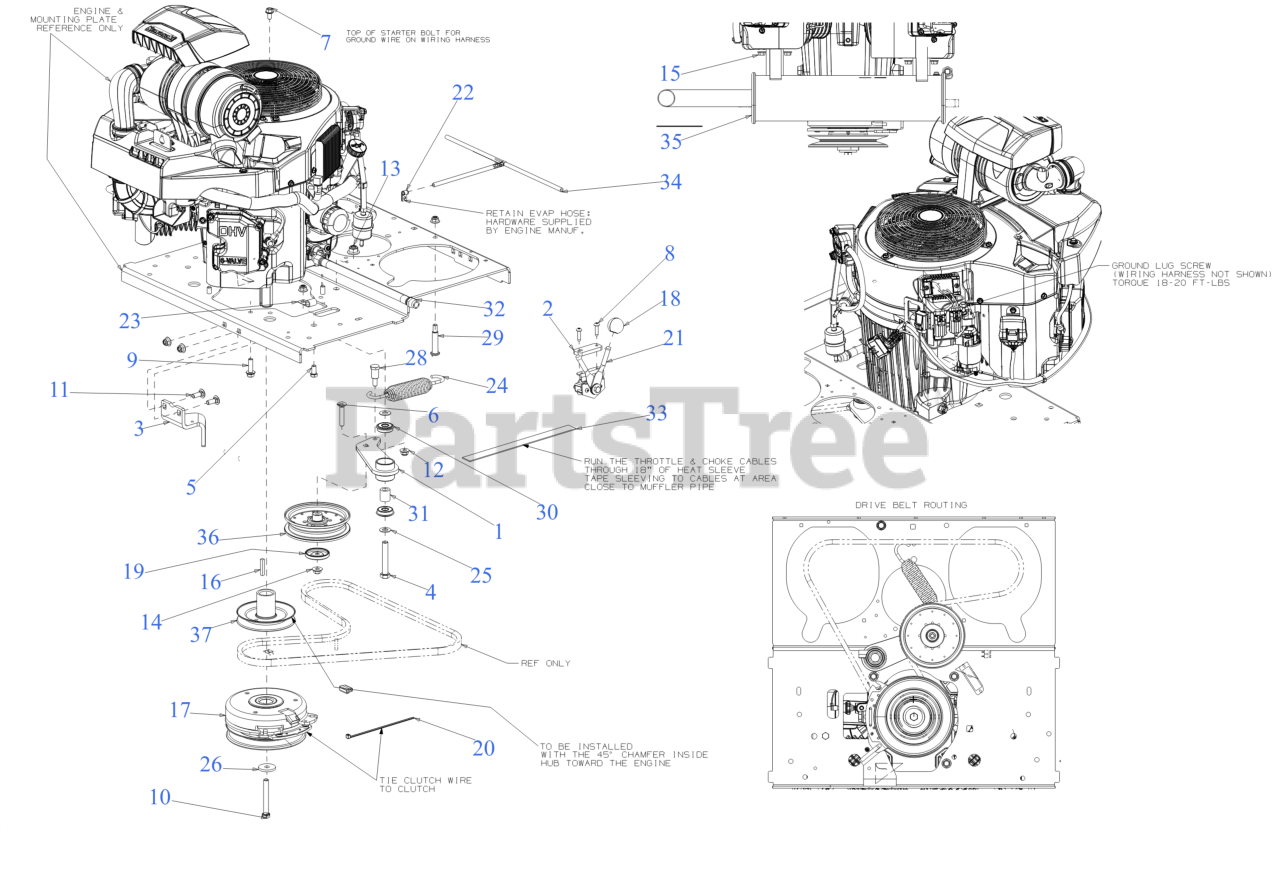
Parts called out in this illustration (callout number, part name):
1	IDLER BRACKET
3	CLUTCH RETAINER BRACKET
4	SCREW-HEX 1/2-13 x 3.00
5	HEX SCREW 3/8-16 x .75
6	CARRIAGE BOLT 3/8-16 x 2
7	SCREW M8 x 1.25 x 16MM GR8.8
8	SCREW 1/4-20 x 1.0
9	SCREW 3/8-16 x 1.25 GR5
10	SCREW 7/16-20 x 3.25 GR5
11	CARRIAGE BOLT 3/8-16 x 1.00 GR5
14	FLANGE LOCK NUT
15	HEX FLANGE NUT
16	SQUARE KEY 1/4 x 1.50
17	ELECTRIC PTO CLUTCH
19	PULLEY CAP
20	7" CABLE TIE
21	ELECTRONIC THROTTLE CONTROL
22	MOUNTING CLAMP
23	J TYPE CLIP
24	EXTENSION SPRING W/HOOK
25	FLAT WASHER .510 x .995
26	FLAT WASHER .45 x 1.5 x .172 HT
28	SHOULDER SCREW .625 x .875 x 3/18
29	SHOULDER BOLT (.50 X 2.0 x 3/8 -16)
30	ROLLER BEARING .5X1.37X.44
31	SPACER 0.51 x 0.88 x 1.00
32	OIL DRAIN HOSE
33	HEAT SHIELD 24"
34	ROLLOVER VENT HOSE ASSEMBLY
35	MUFFLER - KAWASAKI 1000
36	FLAT IDLER PULLEY
37	ENGINE PULLEY
